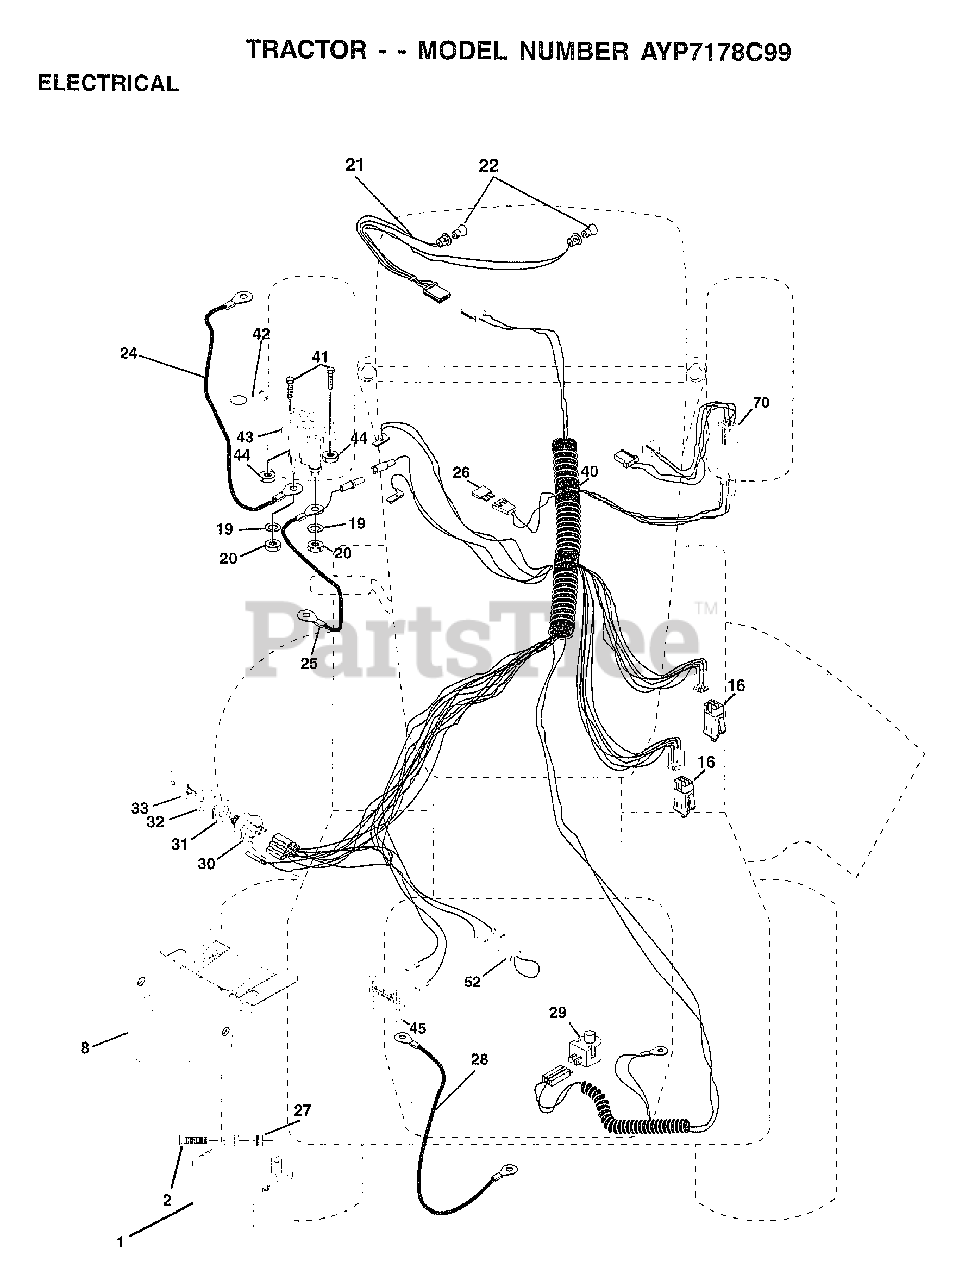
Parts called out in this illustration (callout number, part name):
2	BOLT LT
8	"CASE,BATTERY.MECH"
16	SWITCH INTERLOCK
20	NUT
21	HARNESS.ASM.LIGHT W/4152J
22	HEADLAMP BULB
24	"CABLE T, BATTERY"
25	CABLE.BTRY.6GA.RD
26	FUSE.15 AMP
27	NUT
28	CABLE T
29	SWITCH SEAT
30	SWITCH IGN 4POS
31	NUT IGNITION
32	COVER KEY SWITCH
33	KEY
40	HARNESS.IGNITION
41	BOLT HXHD FIN
44	NUT HXKEP 1/4X20
52	PROTECTION LOOP
70	HARNESS.ENGINE.B&S
